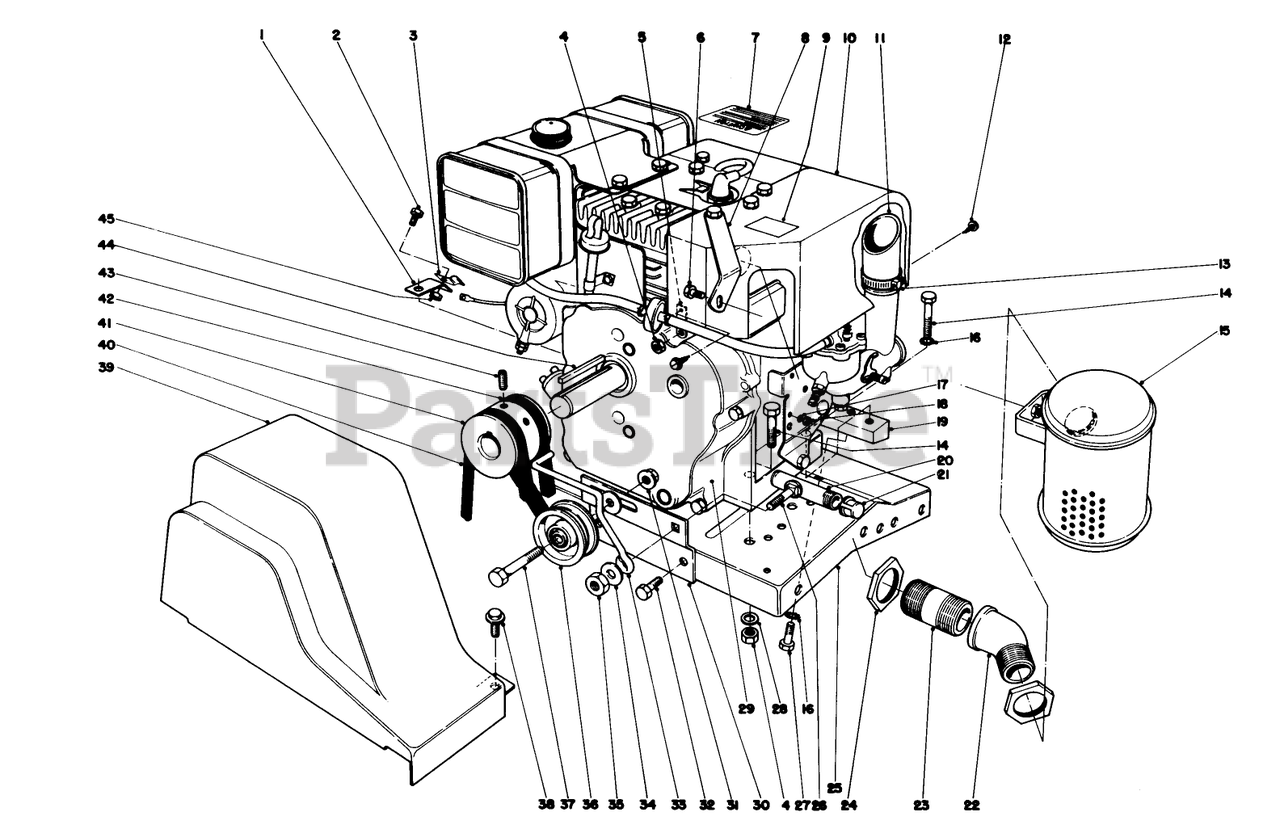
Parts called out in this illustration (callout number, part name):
1	Bracken Wire Clamp
2	SCREW-HWH
3	CABLE CLAMP
4	NUT-LOCK, CONE
5	Standoff-Heater Box
6	5/16-18 X 5/8 SEMS SC
7	Decal Instruction
8	Bracket Muffler Mounting
9	Decal-Tecumseh
10	Heater Box
11	Carburetor Stack
12	SCREW-HWHTF
14	SCREW-HH
15	Muffler
16	WASHER-LOCK
17	WASHER-LOCK/INT
18	NUT-LOCK
19	Block Engine Mounting
20	NIPPLE-PIPE
21	Pipe Cap
22	Elbow
23	Exhaust Pipe
24	Locknut
25	Base-Engine
26	SCREW-CARR
27	SCREW-HH
28	WASHER-PLAIN
29	Engine
30	Belt Idler Bracket
31	NUT-HHF, WHIZ
32	SCREW-HHFTF
33	BELT GUIDE
34	WASHER-FLAT
35	NUT-HEX
36	PULLEY B
37	SCREW-HH
38	SCREW-HWH
39	Belt Guard
40	V-BELT
41	ENGINE PULLEY
42	V-BELT
43	Screw-Set
45	NUT-KEPS
